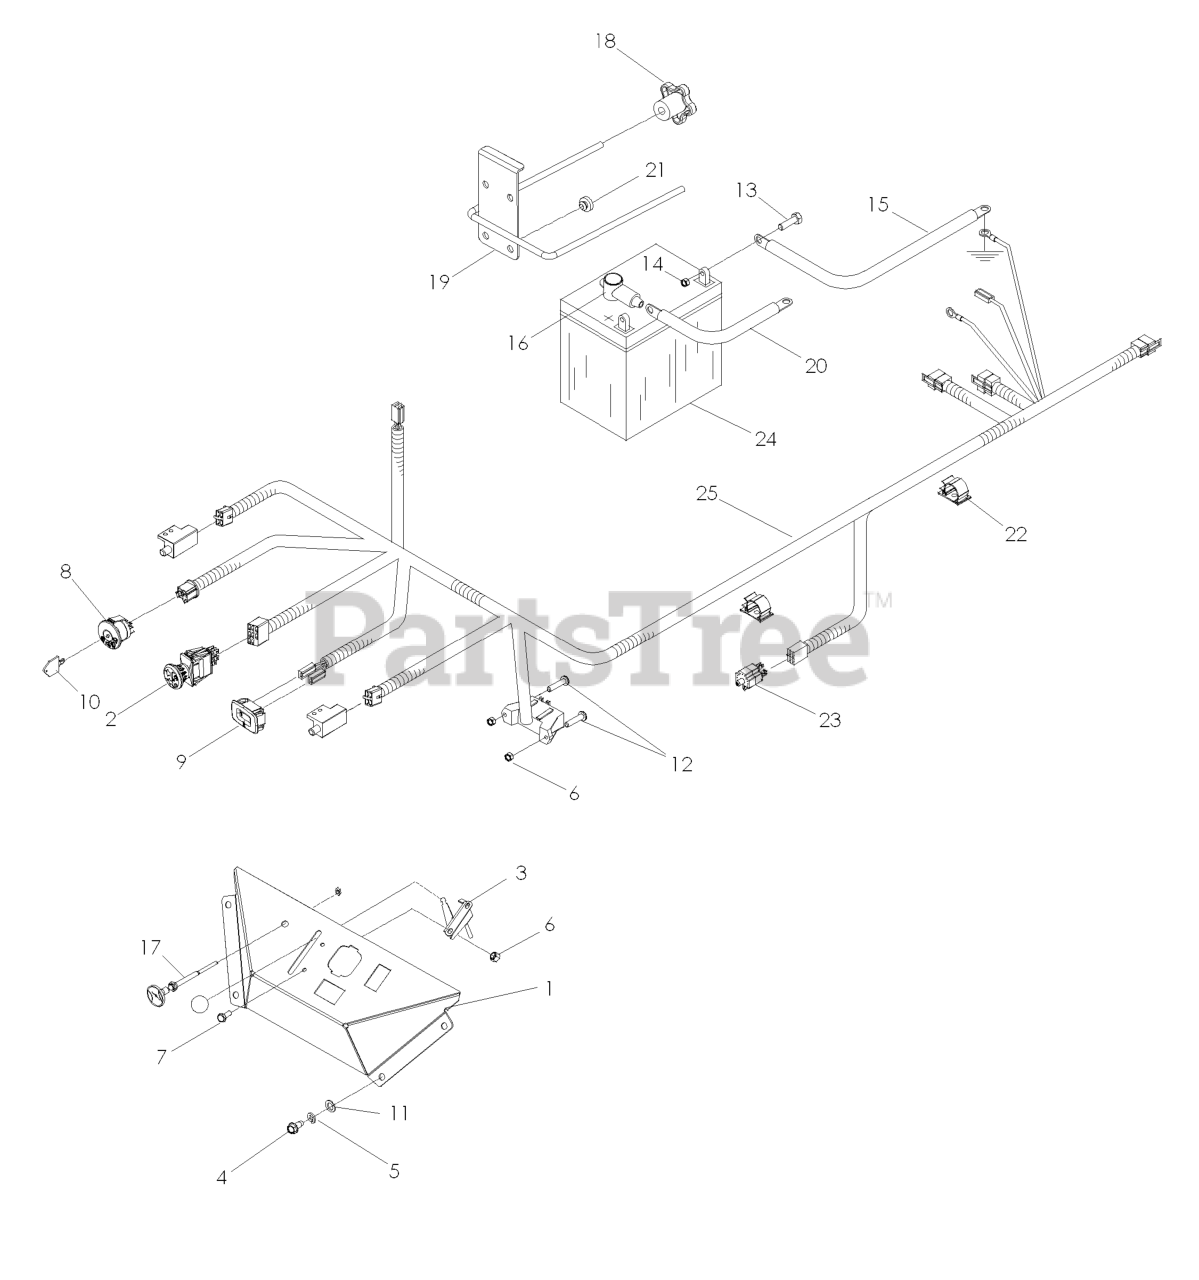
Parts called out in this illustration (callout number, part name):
1	CONSLE, ORANGE
2	SWITCH, PTO 10 AMP
3	THROTTLE CONTROL W/BALL KNOB
4	SCREW 1/4 X 5/8
5	LOCKWASHER 1/4"
6	NUT 10-24 NYLOC
7	HCS #10-24 X 1/2
8	RP IGNITION SWITCH
9	HOUR METER
10	KEY
11	WASHER 1/4 FLAT
12	SCREW, #1--24 X 1/2 SLOTTED
13	HCS 5/16C X 3/4
14	NUT 5/16 NYLOC
15	CABLE-NEGATIVE
17	CONTROL-CHOKE 51"
19	BATTERY HOLD DOWN
20	POST.CABLE LONG
20	CABLE POSITIVE
21	GROMMET, BUMPER
22	PUSH-MOUNT WIRE CLIP
23	SWITCH, BRAKE 3P
24	BATTERY, 12 V 330 AMP
25	HARNESS, WIRING LZ/IZ
